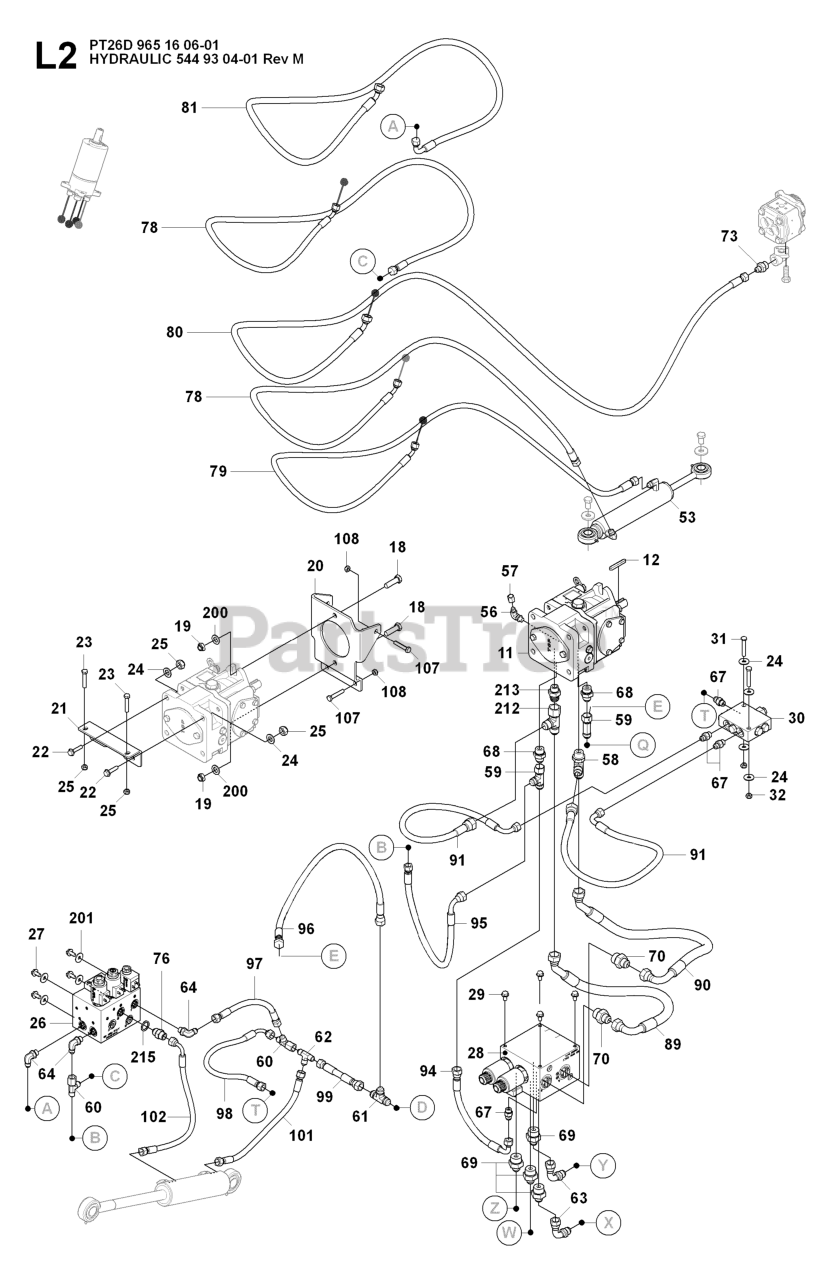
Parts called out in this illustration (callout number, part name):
1	WHEEL MOTOR 125 CW
2	WHEEL MOTOR 125 CCW
3	WHEEL MOTOR 160 CW
4	WHEEL MOTOR 160 CCW
7	COTTER PIN
22	SCREW EHHFM
23	SCREW
24	WASHER BRB 8.4X17
25	LOCKNUT M8
32	LOCKNUT M8
46	FILTER HOLDER
47	LOCKNUT M8
48	LOCKNUT M5
53	HYDRAULIC CYLINDER
58	PIPE FITTING 7/8-7/8
61	PIPE FITTING JIC T 3/4"
62	PIPE FITTING JIC T
74	PIPE FITTING JIC-BSPP STRAIGHT
75	CHECK VALVE 2BAR
96	HYDRAULIC HOSE 3/8"
105	BOLT FLANGE - M8X50
107	Screw M10x25
108	NUT
202	WASHER
205	WASHER BRB 8.4X17
209	HOSE GUARD D=43 L=750
215	O-RING 12X2 NITRIL
